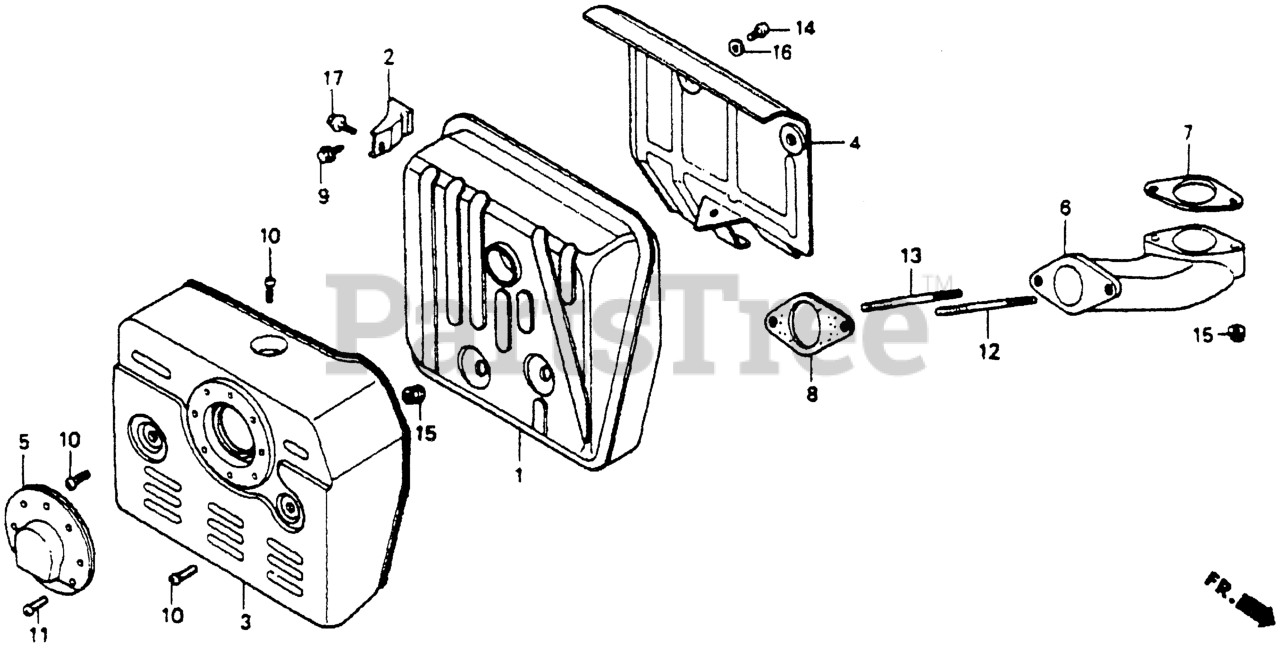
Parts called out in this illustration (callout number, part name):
1	MUFFLER
2	STAY, MUFFLER
3	PROTECTOR, MUFFLER
4	SEPARATOR, MUFFLER
5	CAP, MUFFLER
6	PIPE, EX.
7	GASKET, EX. PIPE Use up to Engine SN 2949254.
7	GASKET, EX. PIPE (WACKER)
8	GASKET, EX. PIPE
9	BOLT, FLANGE (8X16)
10	SCREW, TAPPING (5X8)
11	SCREW, TAPPING (4X6) (TO INSTALL OPTIONAL SPARK ARRESTER)
12	BOLT, STUD (8X60)
13	BOLT, STUD (8X70)
14	SCREW, PAN (6X6)
15	NUT, FLANGE (8MM)
16	WASHER, PLAIN (6MM)
17	BOLT, FLANGE (8X14)
NI	ARRESTER, SPARK
